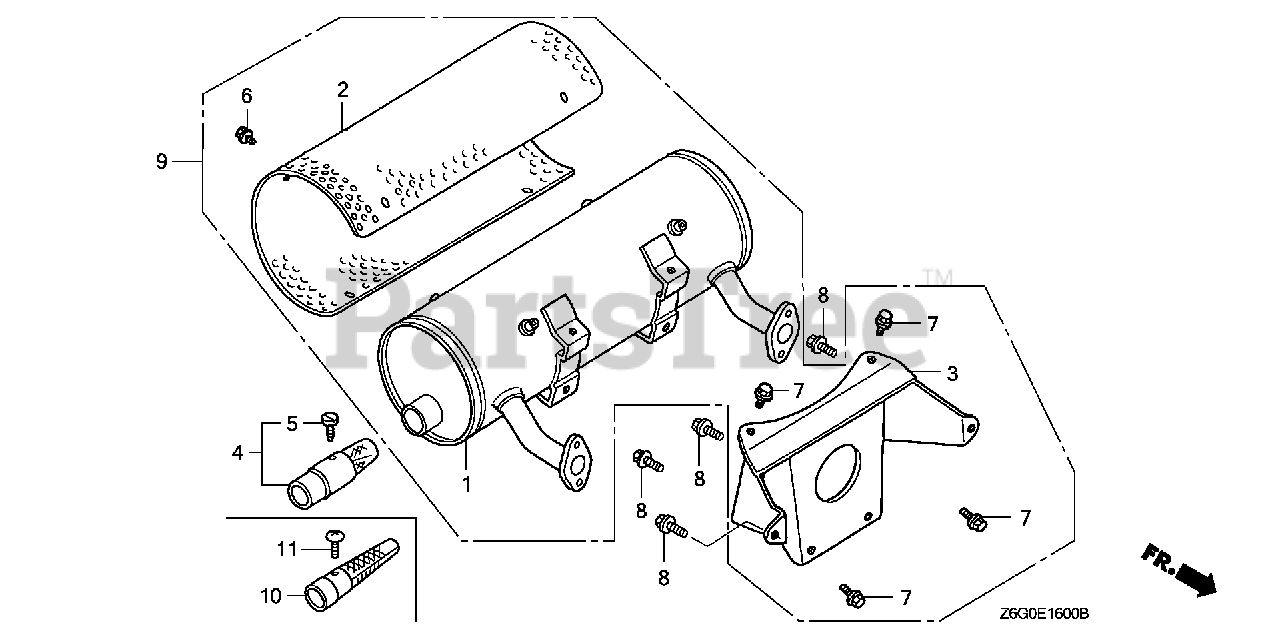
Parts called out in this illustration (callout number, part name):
1	MUFFLER COMP. (HIGH-R) (FUTABA) (SILVER MUFFLER)
1	MUFFLER COMP. (HIGH-R) (NELSON) (BLACK MUFFLER) (N/A: USE #18300-ZJ1-881) (SHIFT18300-ZJ1-880) (IF N/A - #18300-ZJ1-881 RT.)
2	PROTECTOR, MUFFLER (HIGH) (FUTABA) (FOR BLACK MUFFLER)
2	PROTECTOR, MUFFLER (HIGH) (FUTABA) (FOR SILVER MUFFLER)
2	PROTECTOR, MUFFLER (HIGH)(NELSON) (FOR BLACK MUFFLER)
3	STAY, MUFFLER (HIGH-FUTABA) (FOR SILVER MUFFLER)
4	ARRESTER, SPARK (FOR BLACK MUFFLER)
5	SCREW (NELSON) (SCREW UNAVAILABLE SEPARATELY. ORDER DEFLECTOR KIT.)
6	BOLT, FLANGE (6X8)
7	BOLT, FLANGE (8X14)
8	BOLT, FLANGE (8X20) Use up to Engine SN 1609606.
9	MUFFLER ASSY. (HIGH-R) (FUTABA) (SILVER MUFFLER)
10	ARRESTER KIT (HIGH)
10	ARRESTER, SPARK (FOR SILVER MUFFLER)
11	SCREW, TAPPING (5X8) (FOR SILVER MUFFLER)
